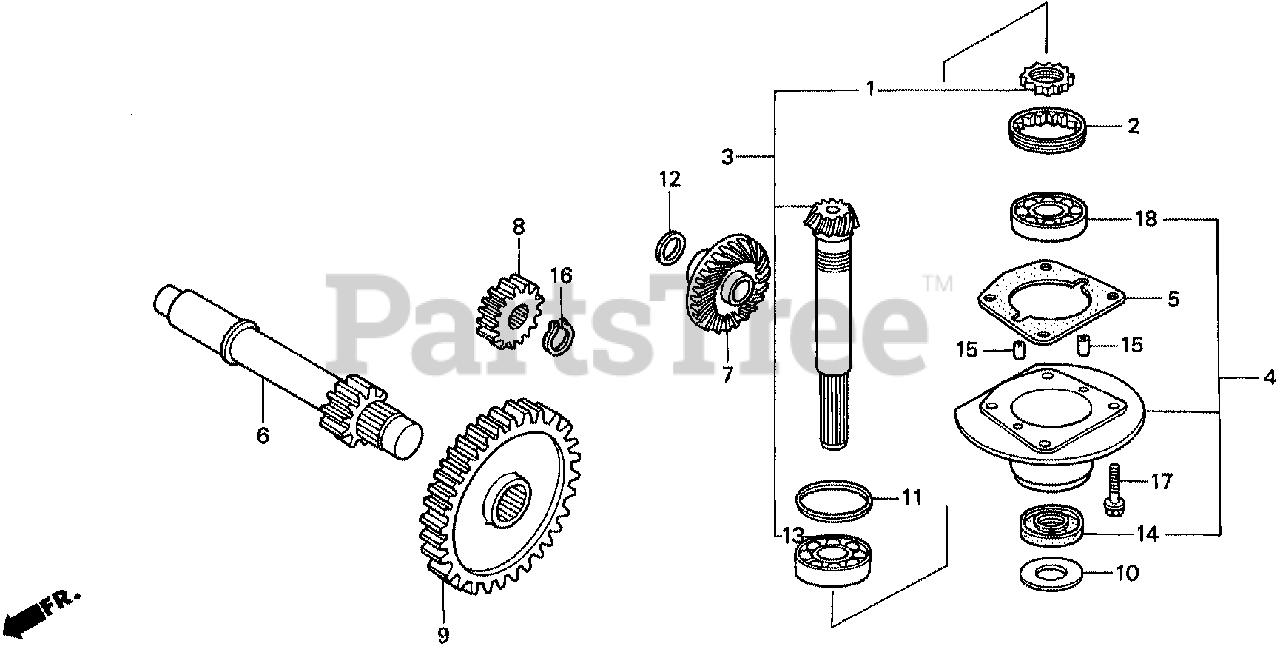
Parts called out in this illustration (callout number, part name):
1	NUT, LOCK (22MM)
2	NUT, LOCK (48MM)
3	SHAFT, INPUT
4	HOLDER, INPUT SHAFT
5	GASKET, INPUT SHAFT HOLDER
6	COUNTERSHAFT
7	GEAR, BEVEL
8	GEAR, COUNTERSHAFT DRIVE (19T)
9	GEAR, COUNTERSHAFT DRIVEN (47T)
10	WASHER (17MM)
11	SHIM A, PINION GEAR (1.25)
11	SHIM B, PINION GEAR (1.30)
11	SHIM C, PINION GEAR (1.35)
11	SHIM D, PINION GEAR (1.40)
11	SHIM E, PINION GEAR (1.45)
11	SHIM F, PINION GEAR (1.50)
11	SHIM G, PINION GEAR
11	SHIM H, PINION GEAR (1.60)
11	SHIM J, PINION GEAR (1.65)
11	SHIM K, PINION GEAR (1.70)
12	SHIM, BEVEL GEAR (1.45) (A)
12	SHIM, BEVEL GEAR (1.50) (B)
12	SHIM, BEVEL GEAR (1.55) (C)
12	SHIM, BEVEL GEAR (1.60) (D)
12	SHIM, BEVEL GEAR (1.65) (E)
12	SHIM, BEVEL GEAR (1.70) (F)
12	SHIM, BEVEL GEAR (1.75) (G)
12	SHIM, BEVEL GEAR (1.80) (H)
12	SHIM, BEVEL GEAR (1.85) (J)
12	SHIM, BEVEL GEAR (1.90) (K)
13	BEARING, RADIAL BALL (60/22) (TMB) (NOT AVAILABLE)
14	OIL SEAL (20X38X8)
15	PIN, DOWEL (6X10)
16	CIRCLIP (OUTER) (15MM)
17	BOLT, FLANGE (8X25)
18	BEARING, RADIAL BALL (6204)
